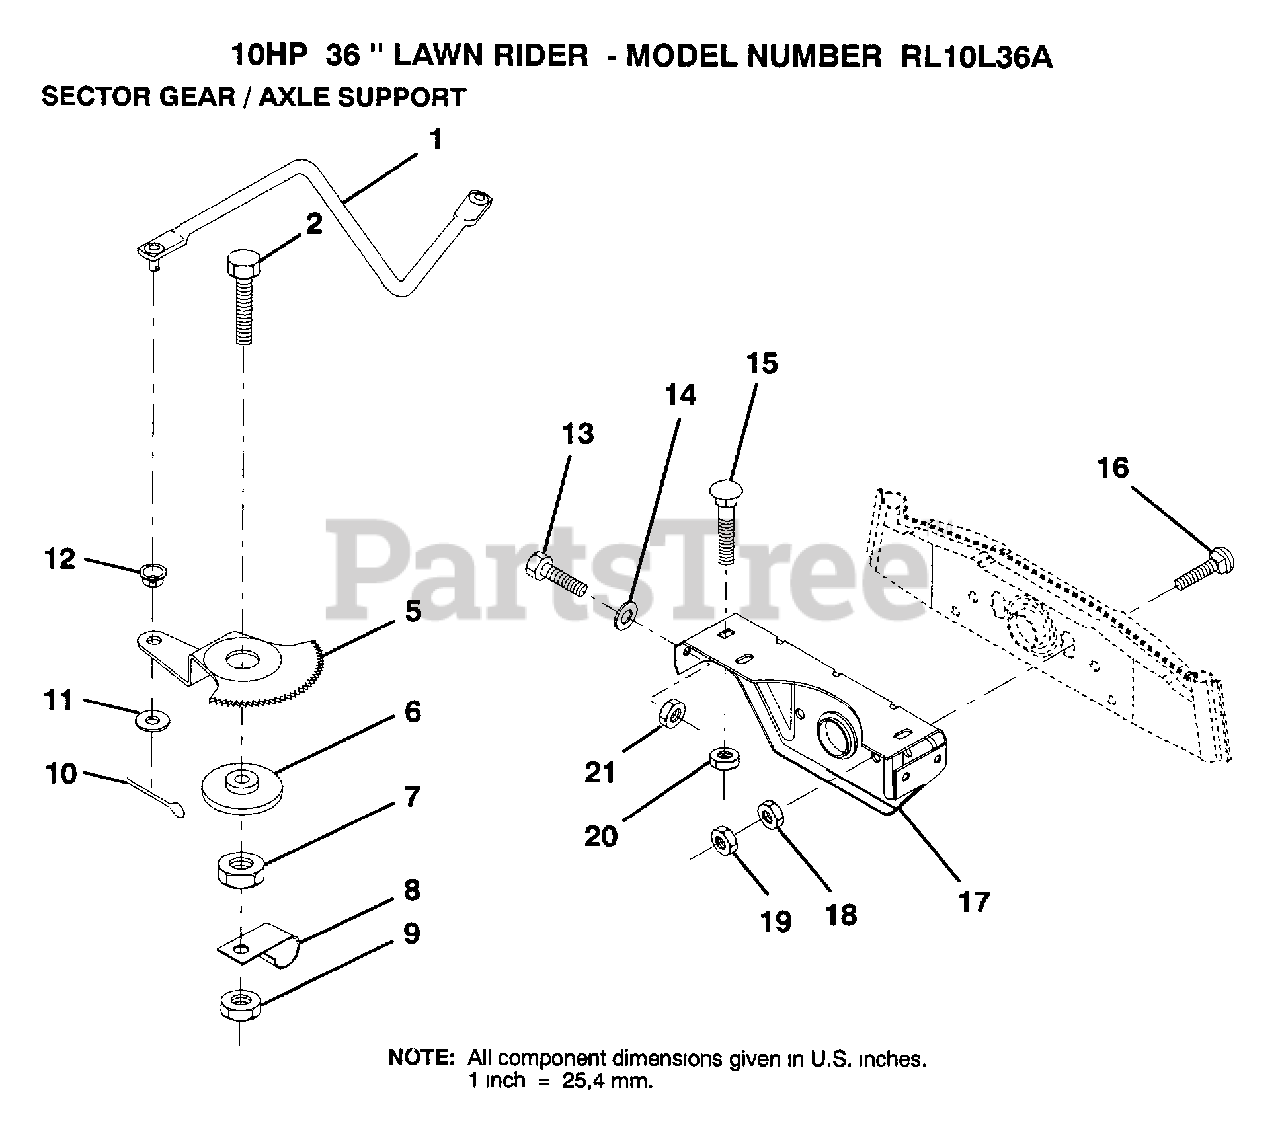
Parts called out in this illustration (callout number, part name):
1	DRAG LINK
2	"BOLT,HEX"
5	GEAR SECTOR
6	BUSHING
7	NUT
8	CLIP INSULATOR
9	NUT LTV
10	COTTER PIN
11	WASHER
12	BUSHING.DRAGLINK
13	BOLT
14	WASHER
15	BOLT
16	BOLT
17	"SUPT,FRT AXLE"
18	NUT.HEX.3/8-16UNC
19	LOCKNUT
